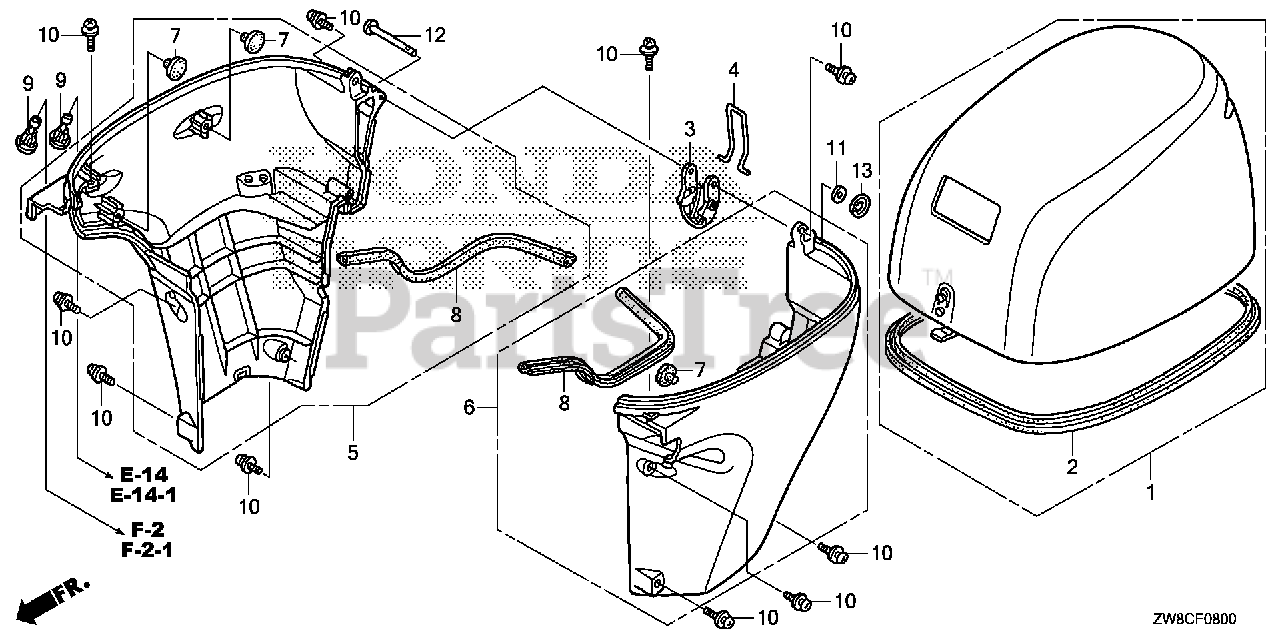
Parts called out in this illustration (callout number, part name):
1	COVER, ENGINE *NHB14M* (AQUA MARINE SILVER METALLIC)
2	SEAL, ENGINE COVER
3	LEVER, FASTENER
4	WIRE, FASTENER (3.2)
5	COVER, R. ENGINE (LOWER) *NHB14M* (AQUA MARINE SILVER METALLIC)
6	COVER, L. ENGINE (LOWER) *NHB14M* (AQUA MARINE SILVER METALLIC)
7	RUBBER, CUSHION
8	SEAL, COVER (LOWER)
9	GROMMET, WATER CHECK
10	BOLT-WASHER, SOCKET (5X10)
11	WASHER, PLAIN (5MM)
12	PIN (5X47)
13	RING, STOPPER
